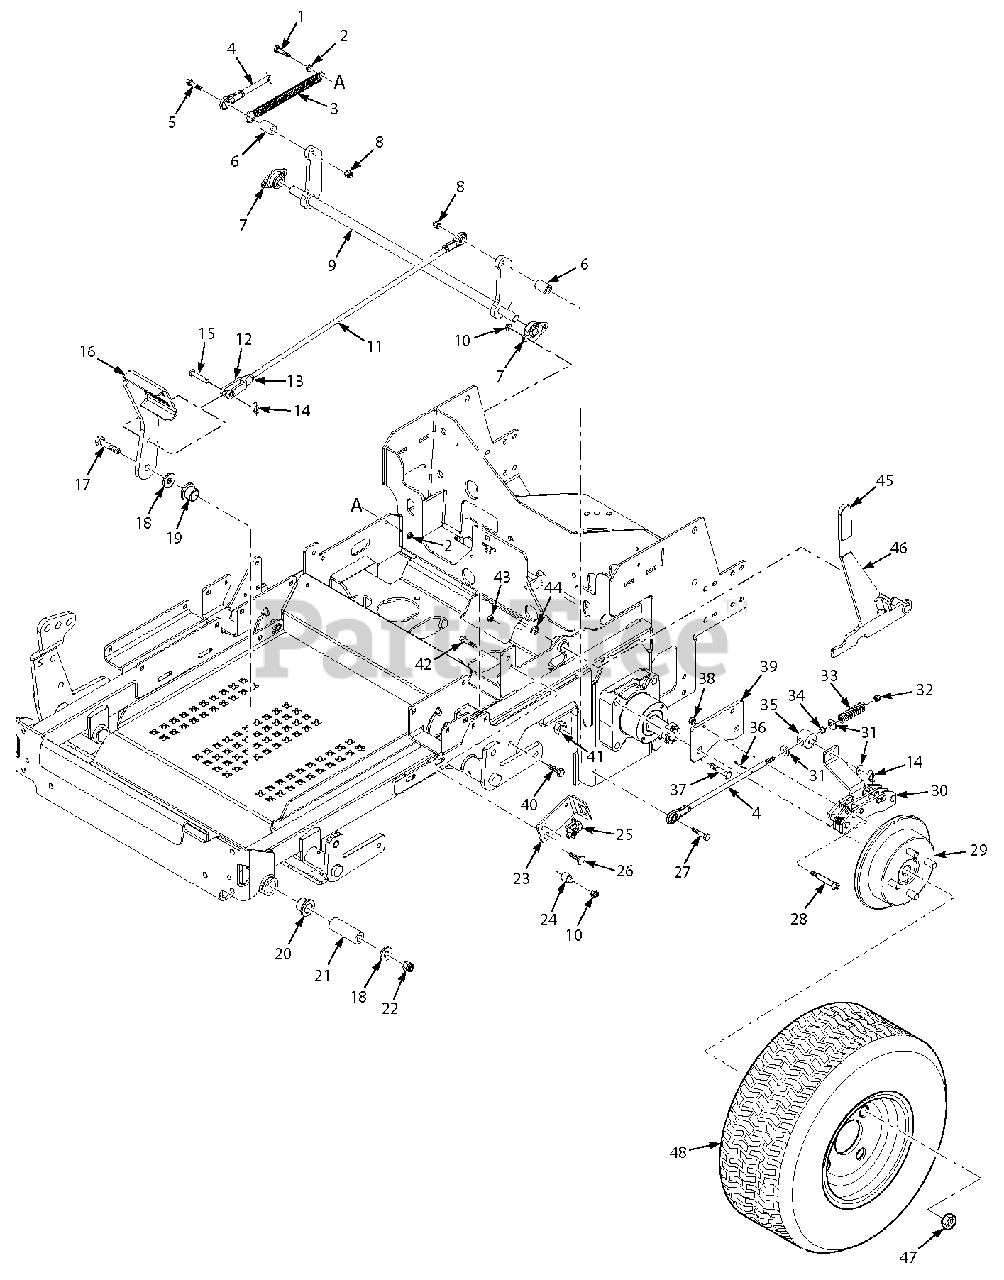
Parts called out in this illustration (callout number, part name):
1	Bolt, Hex Head 1/4-20 x 1-1/4"
2	Nut, Serrated Flange 1/4-20
3	Spring, Brake Return
4	Brake Link Assembly
5	Bolt, Hex Head 3/8-16 x 2-1/2"
6	Spacer
7	Bearing, Self Align - 5/8" I.D.
8	Nut, Flanged Elastic Stop 3/8-16
9	Brake Bellcrank Weldment
10	Nut, Elastic Stop 5/16-18
11	Brake Rod Assembly
11	Rod End, 3/8-24 LH
11	Nut, 3/8-24 UNF LH Jam
12	Clevis
13	Nut, 3/8-24 UNF Jam
14	Pin, Rue Cotter - 3/8" Dia.
15	Clevis Pin, 3/8 x 1.06"
16	Brake Pedal Weldment
17	Bolt, Hex Head 1/2-13 x 4-1/4"
18	Flatwasher, 1/2-.562 x 1.375 x .109
19	Sleeve, Brake Pivot
20	Bearing
21	Sleeve, Brake Pivot
22	Nut, Elastic Stop 1/2-13
23	Switch Mounting Bracket, Brake
24	Spacer
25	Switch
26	Bolt, Carriage 1/4-20 x 3/4"
27	Bolt, Hex Head 3/8-16 x 3"
28	Bolt, 1/2 x 2-3/4" Shoulder
29	Brake Hub
30	Brake Caliper
31	Flatwasher, 3/8-.406 x .812 x .065
32	Nut, Elastic Stop 3/8-24
33	Spring, Brake
34	Bearing
35	Swivel Assembly, Brake
36	Cotter Pin, 3/32 x 3/4"
37	Bolt, Hex Head 1/2-13 x 2-3/4"
38	Nut, Center Lock 3/8-16
39	Mounting Bracket, Brake
40	Bolt, Hex Head 5/16-18 x 3/4"
41	Nut, Elastic Stop 3/8-16
42	Bolt, Hex Head 5/16-18 x 1-3/4"
43	Nut, Elastic Stop 1/4-20
44	Retaining Ring, .625 Ext "E"
45	Grip, Brake Lever
46	Lever w/Grip, Parking Brake
47	Wheel Nut, 1/2-20
48	Wheel Assy 24 x 9.5-12 (48" Deck)
48	Rim (48" Deck)
48	Wheel Assy 24 x 9.5-12 (52" Deck))
48	Rim (52" Deck)
48	Tire 24 x 9.5-12 (48" & 52" Deck)
48	Wheel Assy 24 x 12-12 (61" Deck)
48	Rim (61" Deck)
48	Tire 24 x 12-12 (61" Deck)
